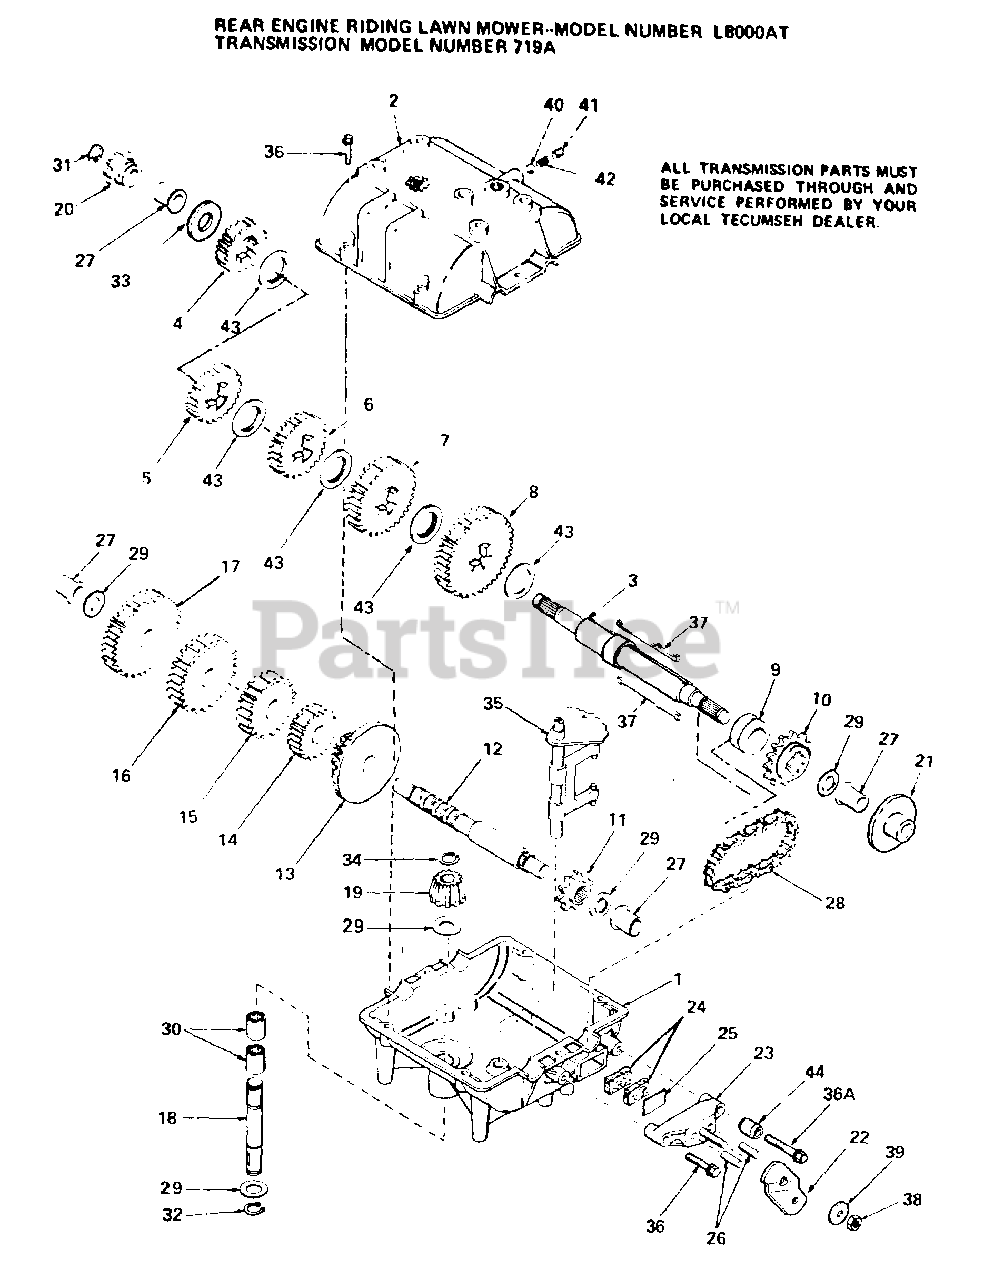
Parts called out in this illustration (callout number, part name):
1	No Desciption for Part
2	No Desciption for Part
3	No Desciption for Part
5	No Desciption for Part
6	No Desciption for Part
7	No Desciption for Part
8	GEAR, SPUR, 35 TEETH
9	COLLAR, SHIFT
10	No Desciption for Part
11	No Desciption for Part
12	No Desciption for Part
13	GEAR, BEVEL
14	No Desciption for Part
15	No Desciption for Part
16	No Desciption for Part
17	No Desciption for Part
18	SHAFT, INPUT
19	No Desciption for Part
20	No Desciption for Part
21	DISK, BRAKE
22	LEVER, BRAKE
23	No Desciption for Part
25	PLATE BRAKE PAD
27	No Desciption for Part
28	No Desciption for Part
29	WASHER THRUST
30	No Desciption for Part
31	No Desciption for Part
32	RING, RETAINER
33	WASHER, THRUST
34	RETAINING RING
35	No Desciption for Part
36	SCREW, 1/4-20 X 1-1/4
36A	SCREW FLNG HEX 1/4-20 X 2-1/4
37	KEY (4 REQUIRED)
38	LOCKNUT 5/16-24
39	WASHER, FLAT
40	BALL STEEL, 5/16" DIA.
41	SCREW, 3/8-16 X 3/8"
43	WASHER THRUST
